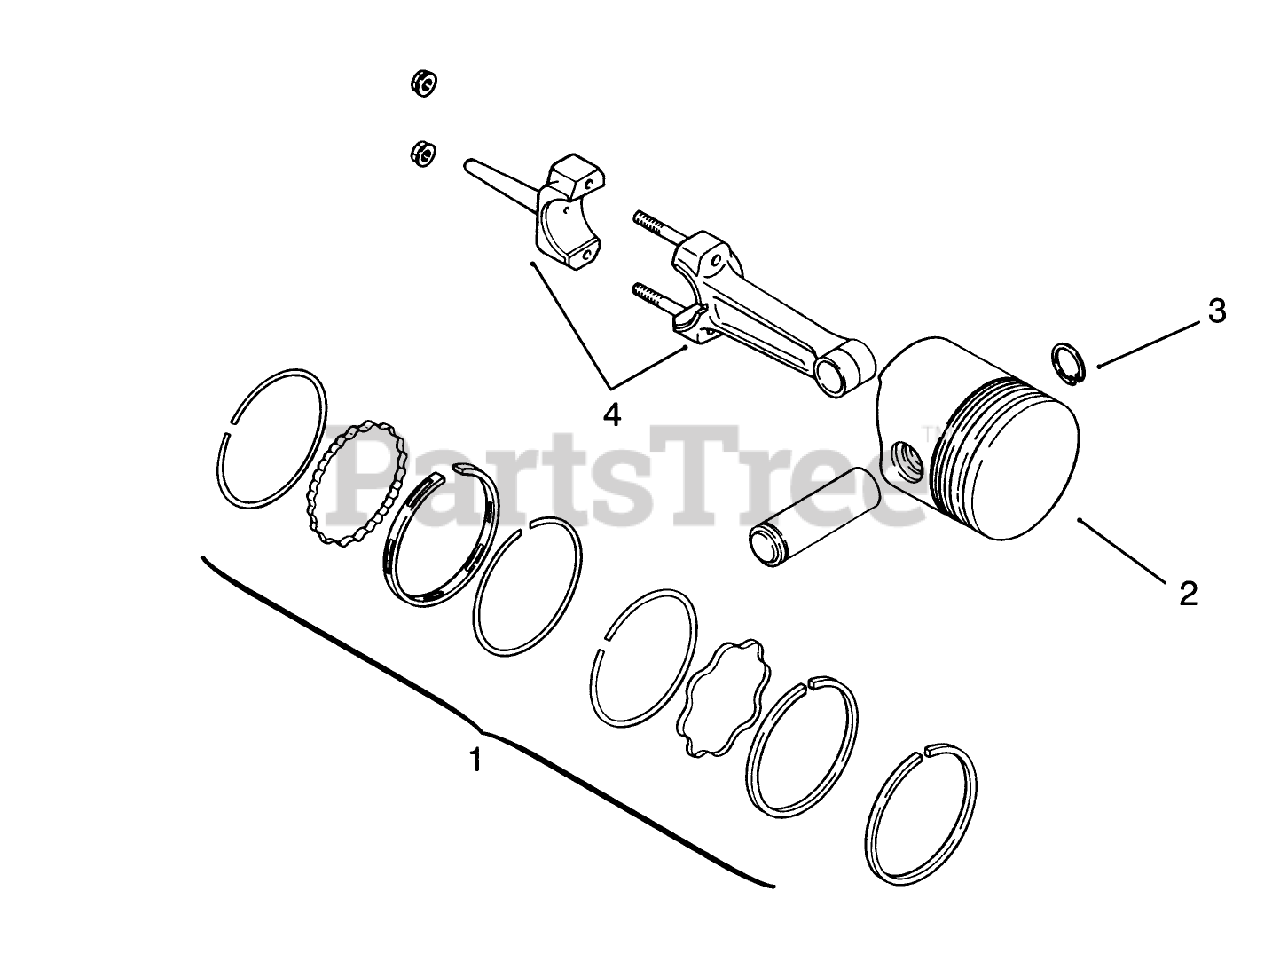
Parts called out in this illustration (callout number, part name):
1	KOHLER 235287
2	KOHLER 47-874.01
3	KOHLER 47-018-01
4	KOHLER 47-067-13
